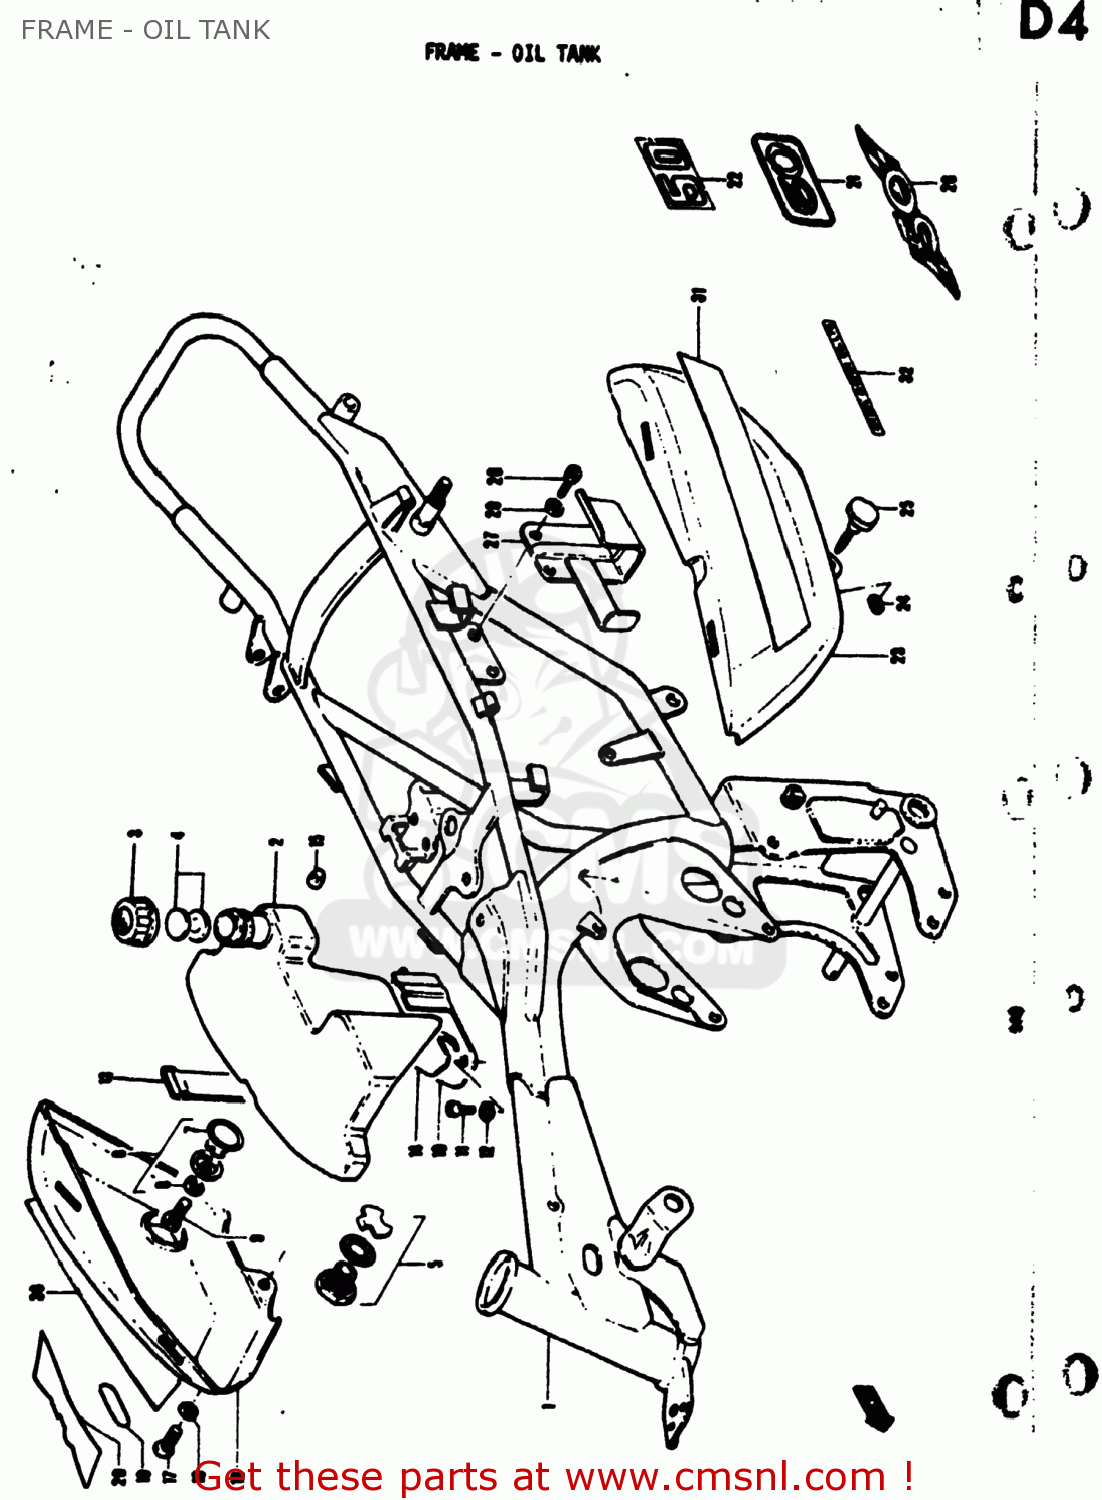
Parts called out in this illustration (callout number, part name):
1	FRAME
2	TANK,OIL
3	CAP,OIL TANK
4	GASKET SET,OIL TANK CAP
5	LENS SET,OIL LEVEL
6	LENS SET,OIL INSPECTION
7	O RING(D:3,ID:23)
8	GASKET(5X9.5X1) (NAS)
9	SCREW
12	LOCK WASHER
13	BAND
14	CUSHION
15	CUSHION
16	COVER,FRAME,RIGHT
17	SCREW
18	WASHER(6.5X16X1.2)
19	EMBLEM,CCIS
20	EMBLEM,FRAME COVER
21	EMBLEM,FRAME COVER
22	EMBLEM
23	COVER,FRAME,LEFT
24	NUT (5MM)
25	KNOB,FRAME COVER
26	EMBLEM,FRAME COVER
27	HOLDER,TOOL
28	SCREW(6X10)
29	LOCK WASHER
30	TAPE,FRAME COVER
31	TAPE,FRAME COVER
32	LABEL,COMPANY NAME
